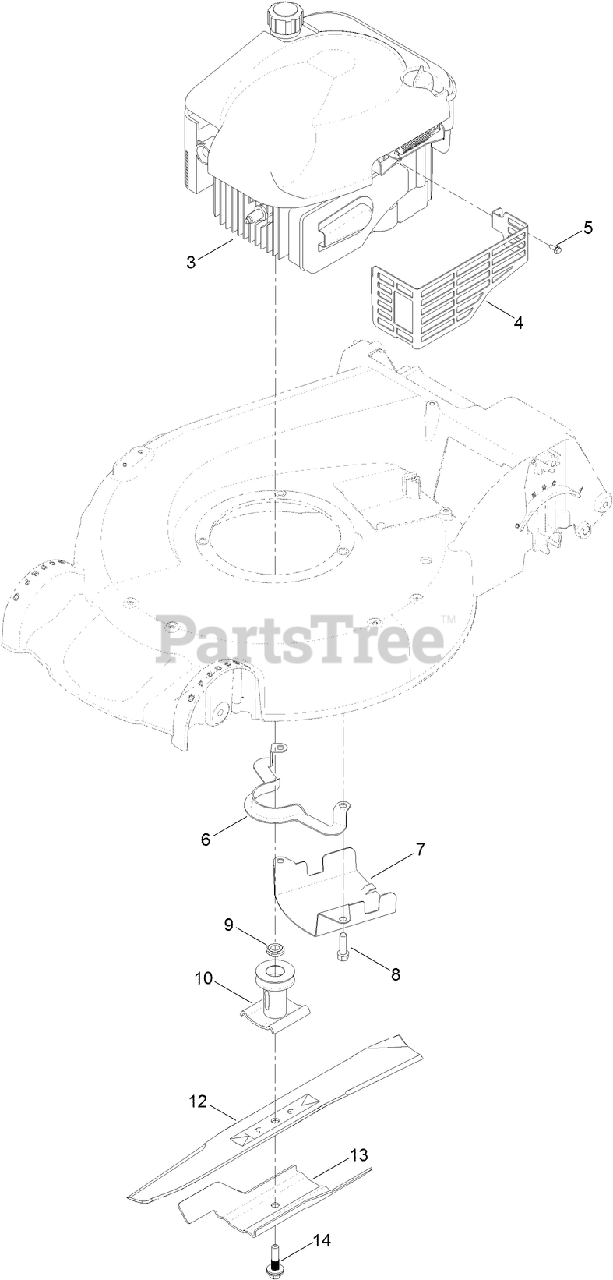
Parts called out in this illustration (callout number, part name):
4	SHIELD-MUFFLER
5	SCREW-TAPTITE
6	GUIDE-BELT
7	SHIELD-GRASS
8	SCREW-TAPTITE
9	Spacer-Driver
10	DRIVER-BLADE
12	BLADE-RECYCLING
13	Accelerator-Blade
14	BOLT-BLADE
